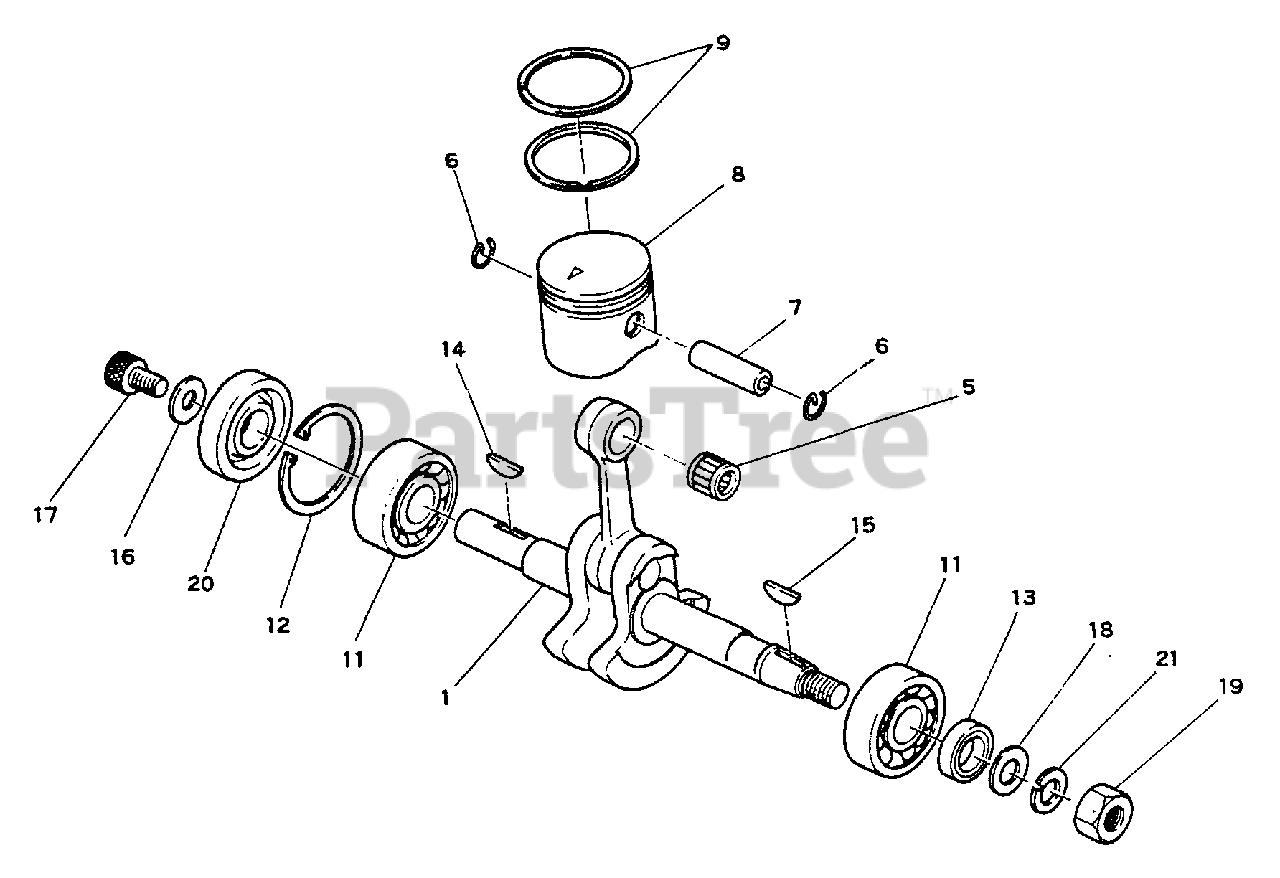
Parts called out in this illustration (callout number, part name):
1	CRANKSHAFT ASSY
5	BEARING, NEEDLE
6	RING, RETAINING
7	PIN, PISTON
8	PISTON
9	RING, PISTON
11	BEARING, BALL - 6201
12	RING, RETAINING - 32
13	SEAL, OIL
16	WASHER - 6
17	SCREW - 6X10
20	SEAL, OIL
21	LOCKWASHER - 8
